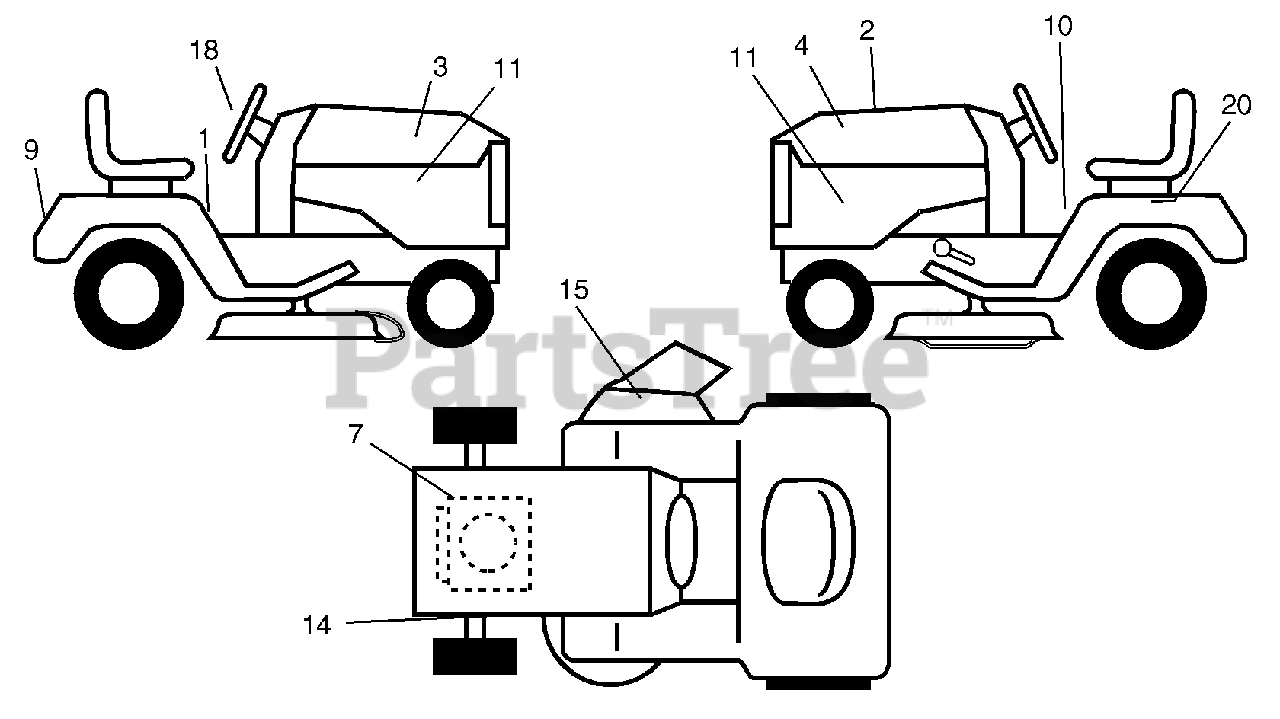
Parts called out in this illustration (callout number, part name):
1	Decal, Oper. Instr.
2	Decal, Replacement
3	Decal, Hood, R.H.
4	Decal, Hood, L.H.
7	Decal, HP Engine
9	Decal, Fender
10	Decal, Fender Danger
11	Decal, Hood Side
13	Decal, Dash Panel
14	Decal, V-Belt Schematic
15	Decal, Deck B 42"
18	Decal, Steering
20	Decal, Battery Dngr/Psn Eng
